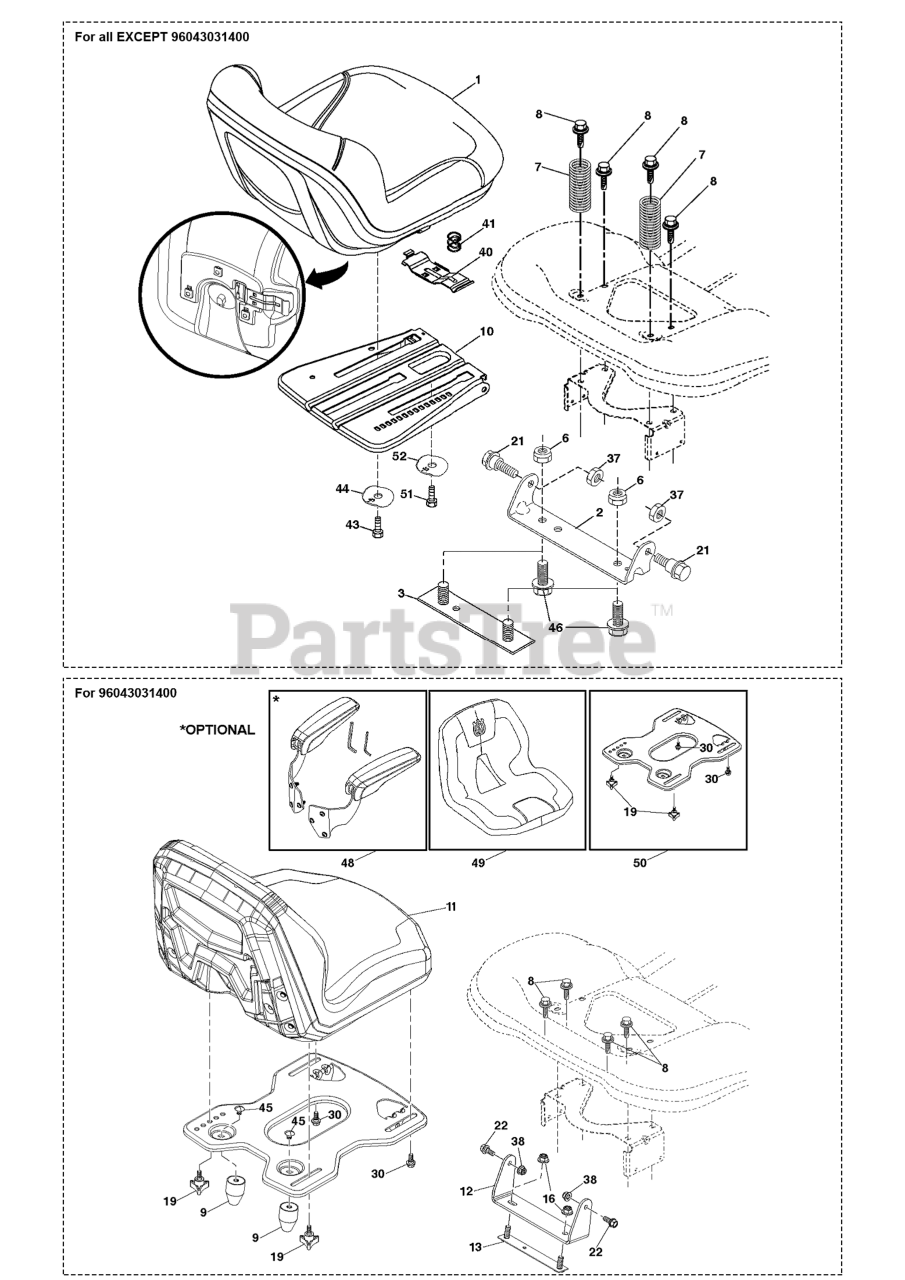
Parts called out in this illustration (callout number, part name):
1	SEAT.TH110.HUSQ.TEX.GREY
1	SEAT.TH130.GREY.HUSQ.TEX
1	SEAT.TH150.MS498.GRY.HUSQ.TEX
2	BRKT.PIVOT.FENDER
3	STRAP
6	NUT
7	SPRING.COMPRESS.SEAT.TAPERED
7	SPRING.COMPRESSION.SEAT.BLACK
8	BOLT.5/16-18UNCX3/4 W/SEMS.BLK
10	PLATE SEAT; SLIDE; 3PT BLACK;
13	BRACKET ASSEMBLY REINFORCEMENT
19	GSPW Knobs
21	BOLT.5/16-18X5/8.SHOULDER
37	Hardware
37	Nuts
38	NUT HEXAGON FLANGE 5/16-18 ST
40	Handles
40	HANDLE.SLIDE.SEAT.TEX.BLACK
41	SPRING.LATCH.SEAT.TEX
44	WASHER.WINGED.3/8ID.1.5OD
44	WASHER.13/32x2 3/8x12GA
46	BOLT.3/8-16X1;1.25OD.WSHR.SEMS
48	ARMREST KIT
50	Service Kit
51	BOLT
52	WASHER.WINGED.3/8ID.1.5OD
